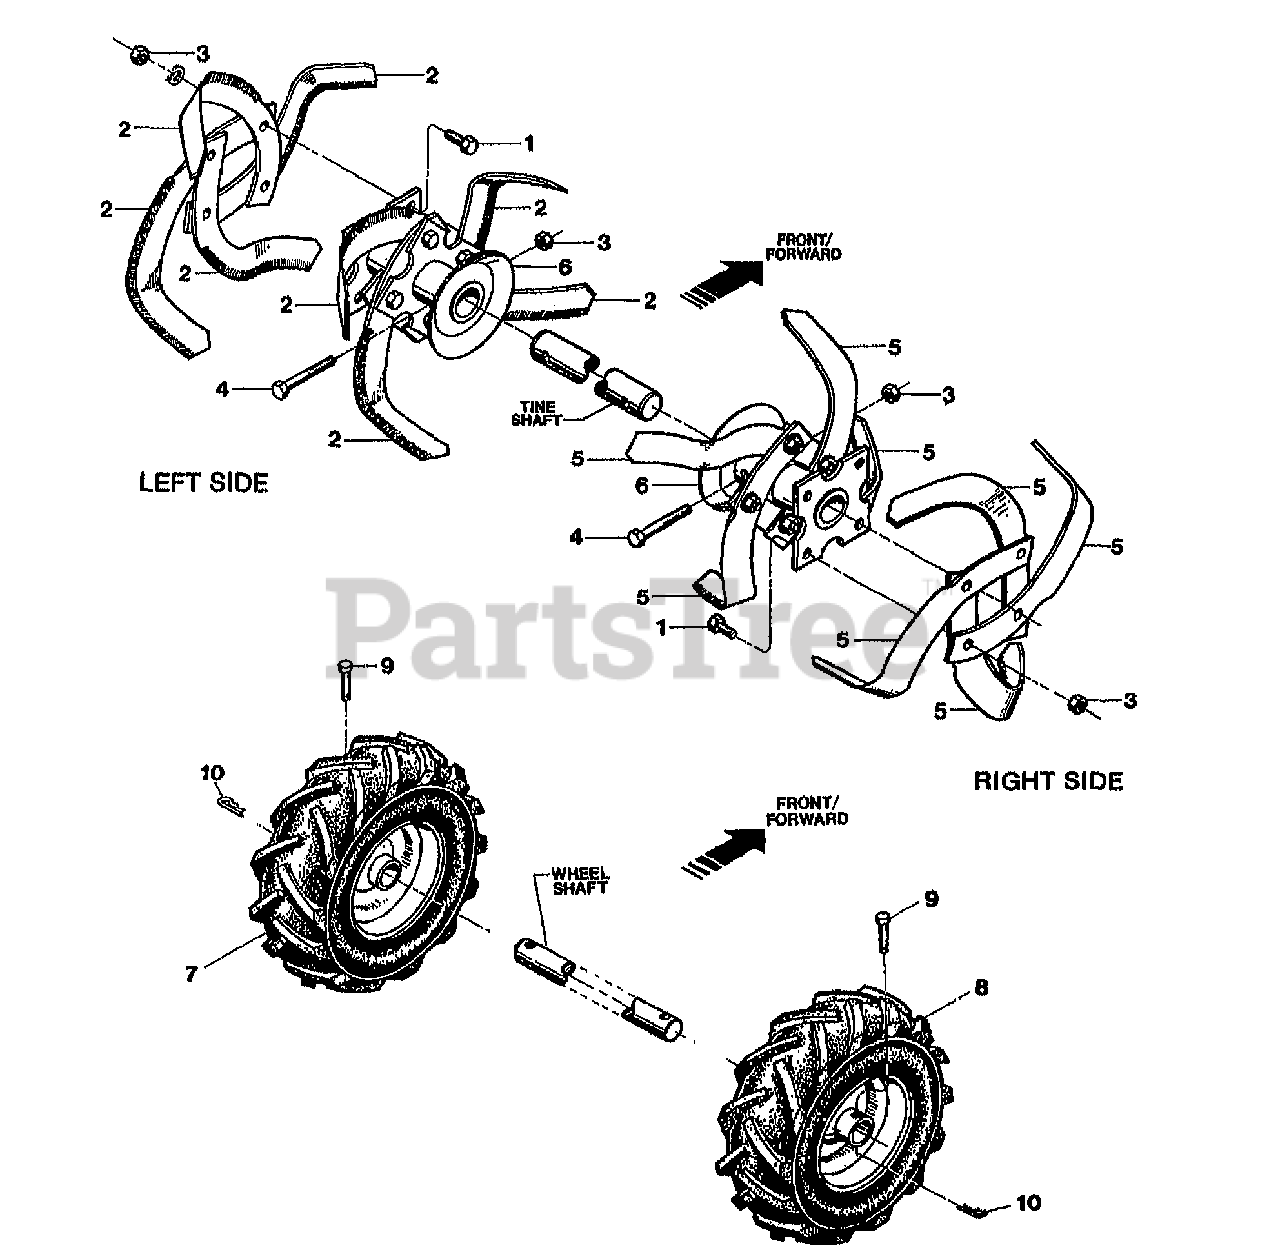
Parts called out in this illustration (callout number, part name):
1	SCR-HH 3/8-16X1.0 G5 ZP
2	TINE-BOLO RIGHT
3	NUT-H/LK 3/8-16
4	BOLT-HH 3/8-16X1.75 G8 ZP (TINE HOLDER TO TILLER SHAFT)
5	TINE-BOLO LEFT
6	HOLDER-TINE PNT
7	ASSM-TIRE&WHL LH GRAY
8	ASSM-TIRE&WHL RH GRAY
9	PIN-CLEVIS
10	PIN-CLIP .08
